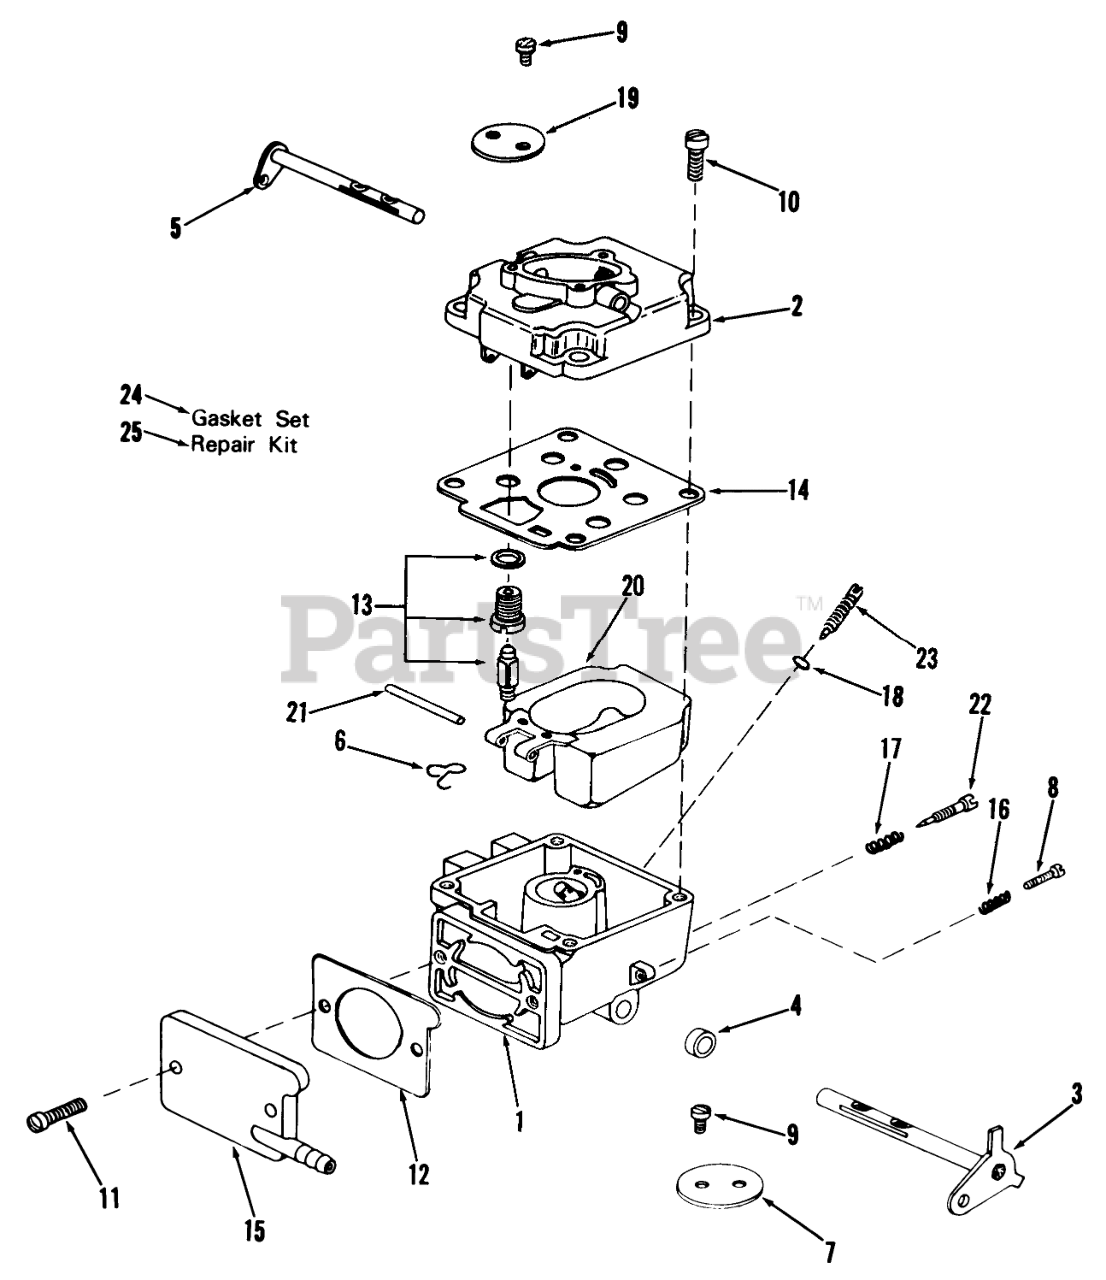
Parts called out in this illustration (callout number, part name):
1	Lower Body Assy
2	Sleeve Assy
3	Shaft-Throttle
4	Packing Shaft
5	SHAFT-CHOKE
6	CLIP-FLOAT VALVE
7	Throttle Fly
8	Screw-Throttle Stop
9	Screw-Fly Mounting
10	SCREW-BOWL COVER MTG
11	Screw-Inlet Plate
12	Gasket-Plate
13	Float Valve Assy
14	GASKET
15	Carburetor Inlet Plate
16	Spring-Throttle Stop
17	Spring-Idle Needle
18	GASKET-O RING
19	Choke Fly
20	Float & Lever Assy
21	Shaft,Float Lever
22	Idle Needle
23	High Speed Needle
